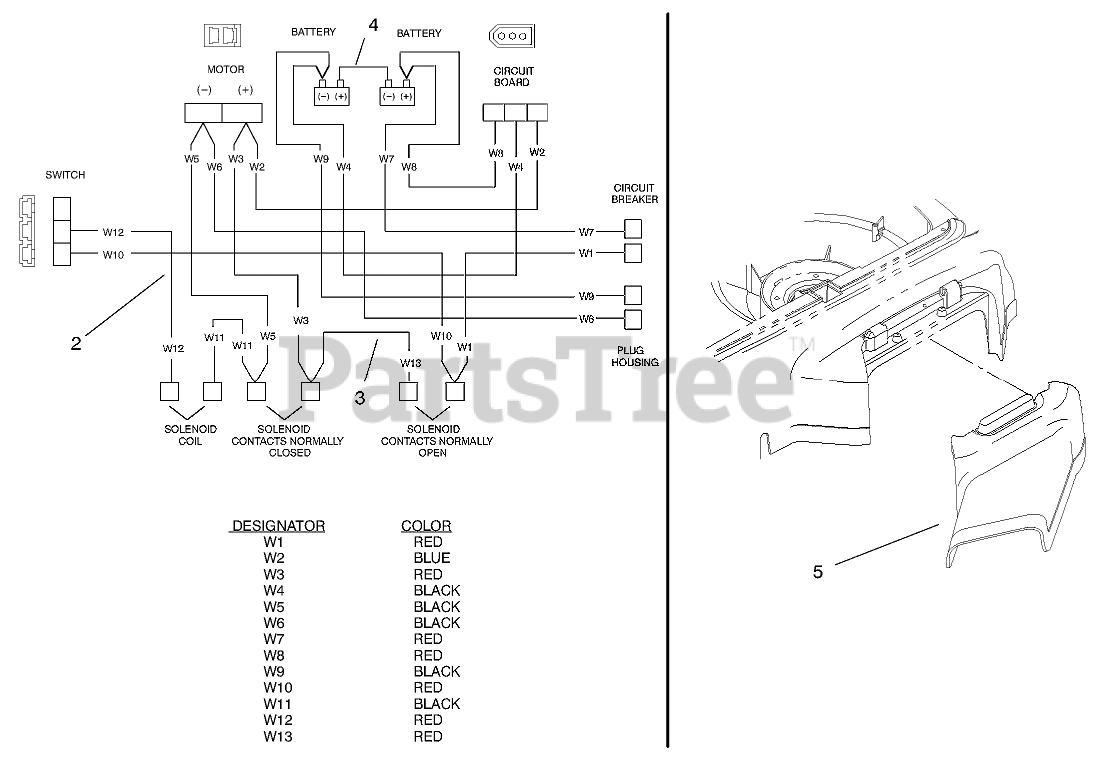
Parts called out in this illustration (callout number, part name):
2	HARNESS-WIRE 24 & 36 VOLT
3	HARNESS-WIRE JUMPER
4	HARNESS
5	CHUTE - SIDE
